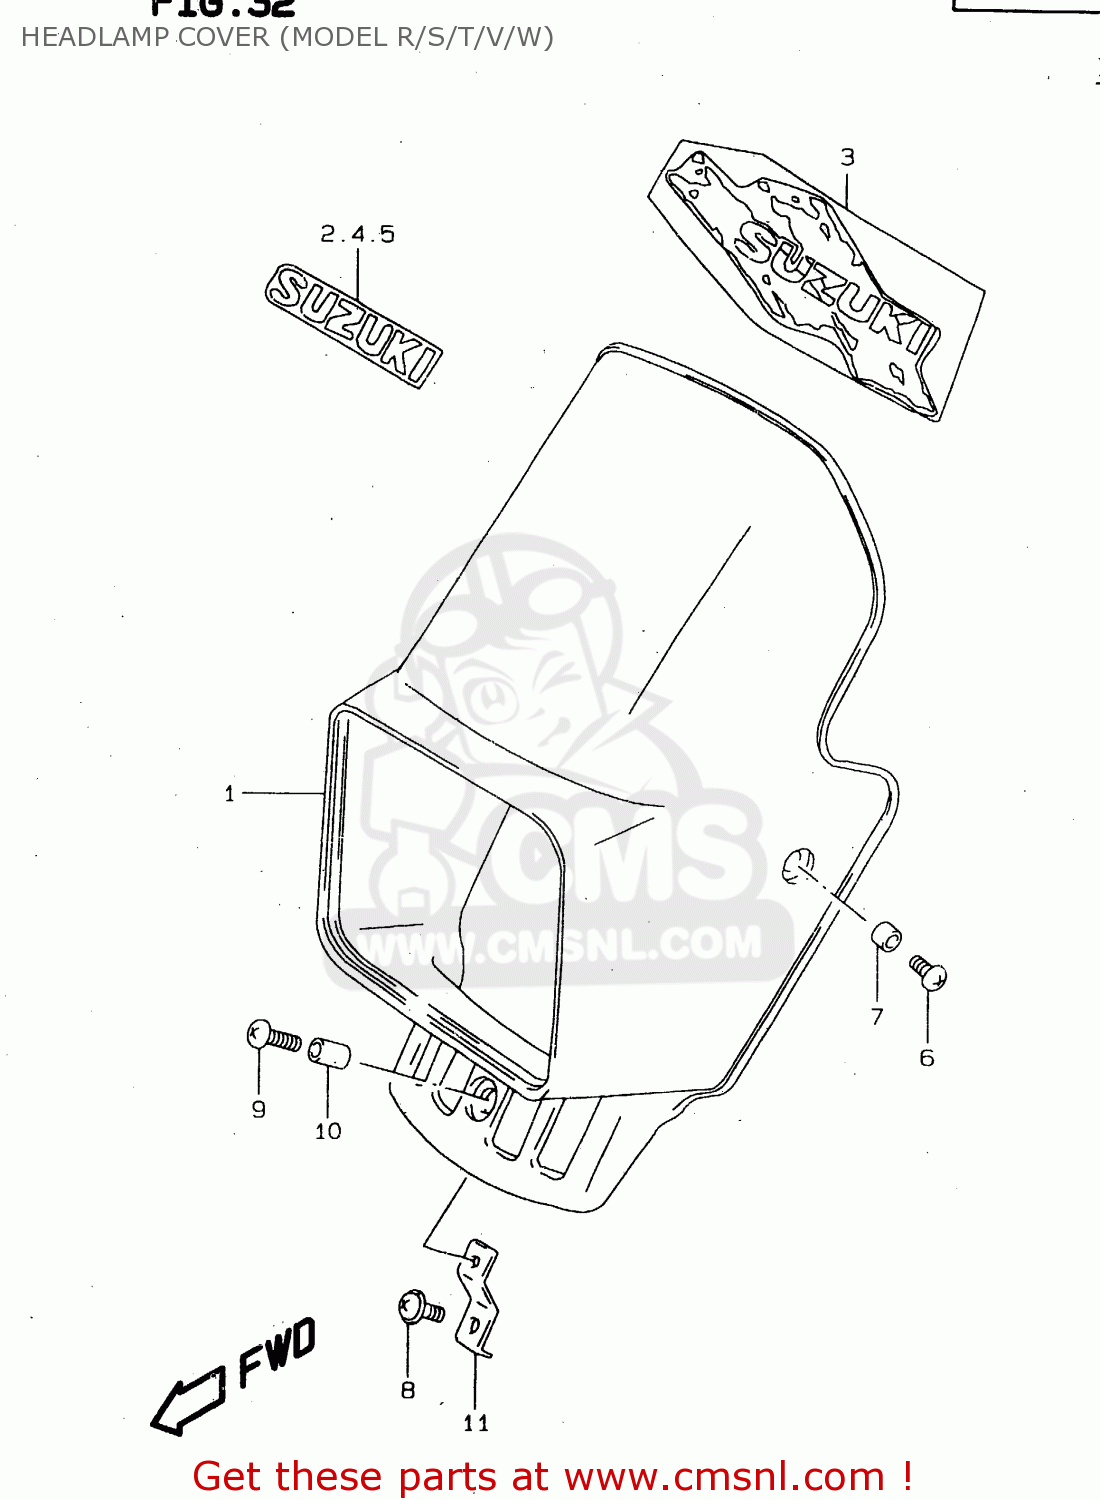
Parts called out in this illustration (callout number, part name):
1	COVER,HEADLAMP
2	EMBLEM,HEADLAMP COVER
3	TAPE,HEADLAMP COVER
4	EMBLEM,SUZUKI
5	EMBLEM
6	SCREW 6X12
7	SPACER(6.1X8X3.5)
8	SCREW
9	SCREW
10	SPACER(6.1X8X12)
11	BRACE,HEADLAMP HOUSING LWR
